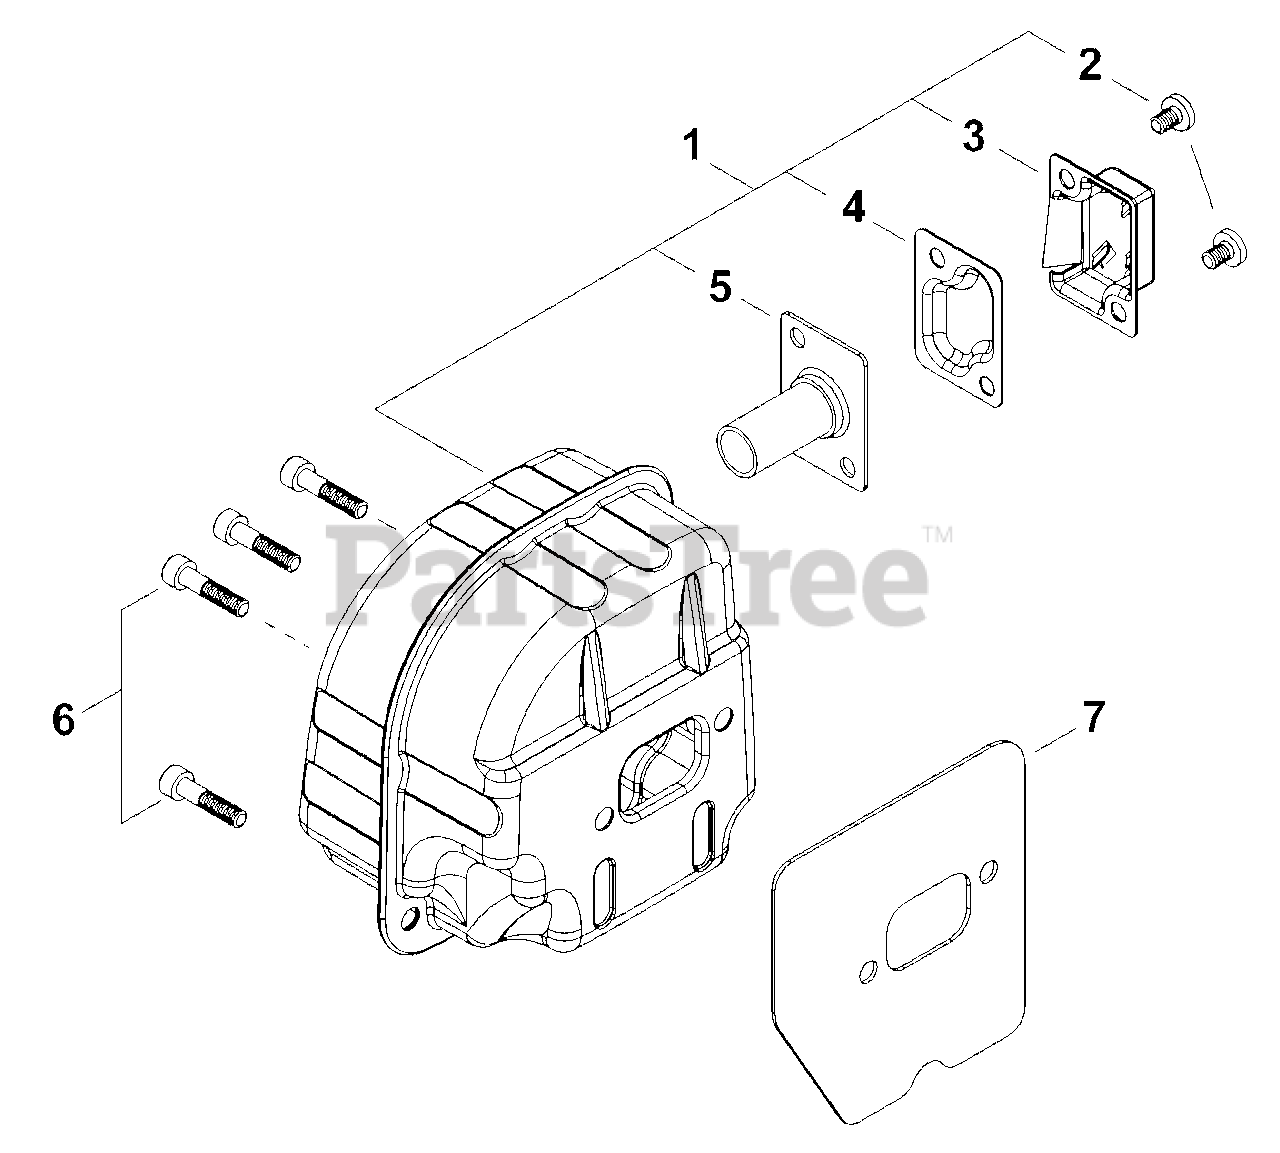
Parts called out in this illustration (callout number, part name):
1	MUFFLER ASSY
2	SCREW M4×6
3	OUTLET, EXHAUST
4	SCREEN, SPARK ARRESTER
5	GUIDE, EXHAUST
6	BOLT M5×18
7	GASKET, EXHAUST
